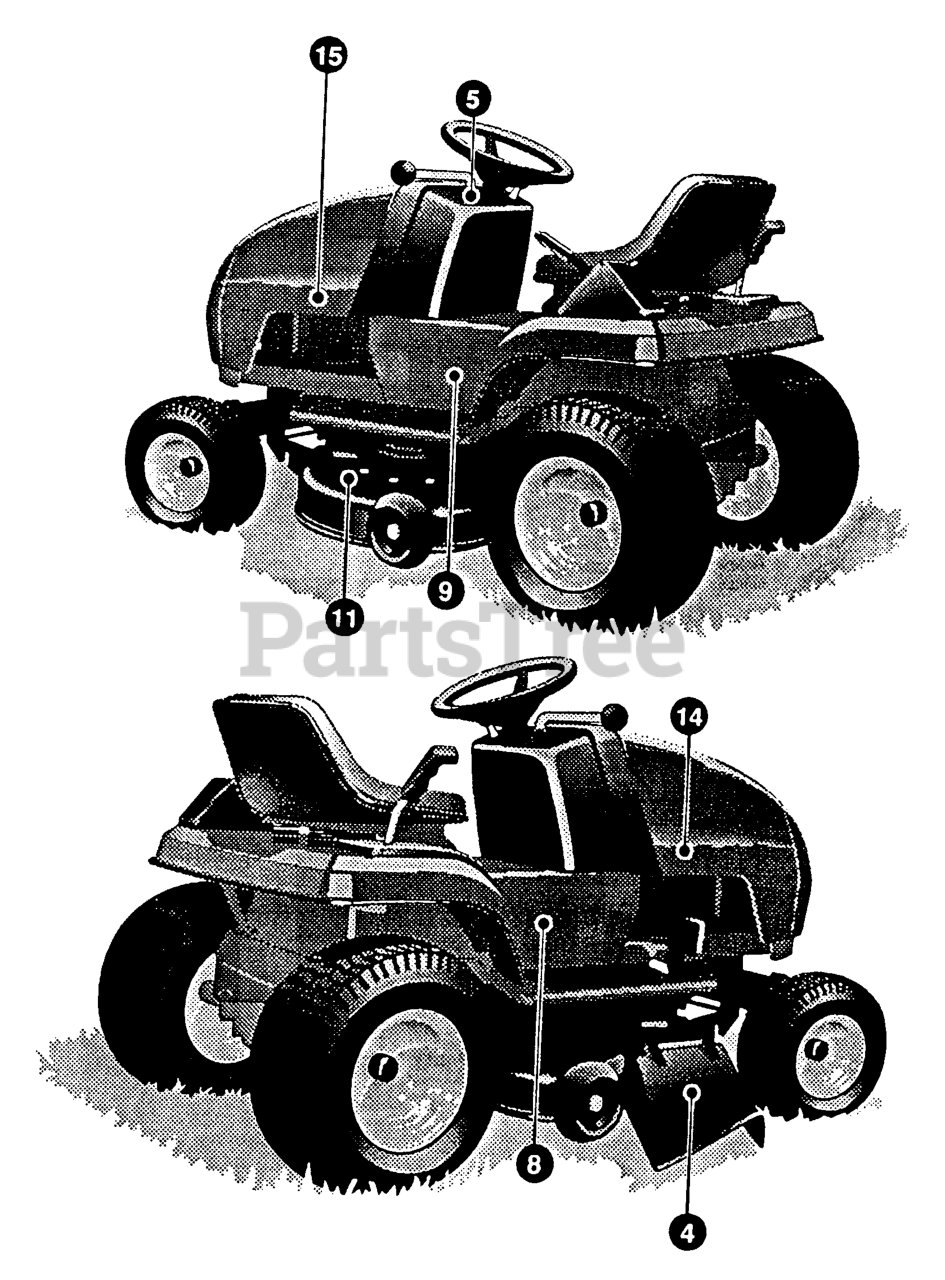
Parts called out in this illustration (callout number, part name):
4	MULCHING KIT INSTALLED
8	43" CONSOLE (RH)
9	43" CONSOLE (LH)
11	MOWER DECK
14	HOOD, 14.5HP
15	HOOD, 14.5HP
